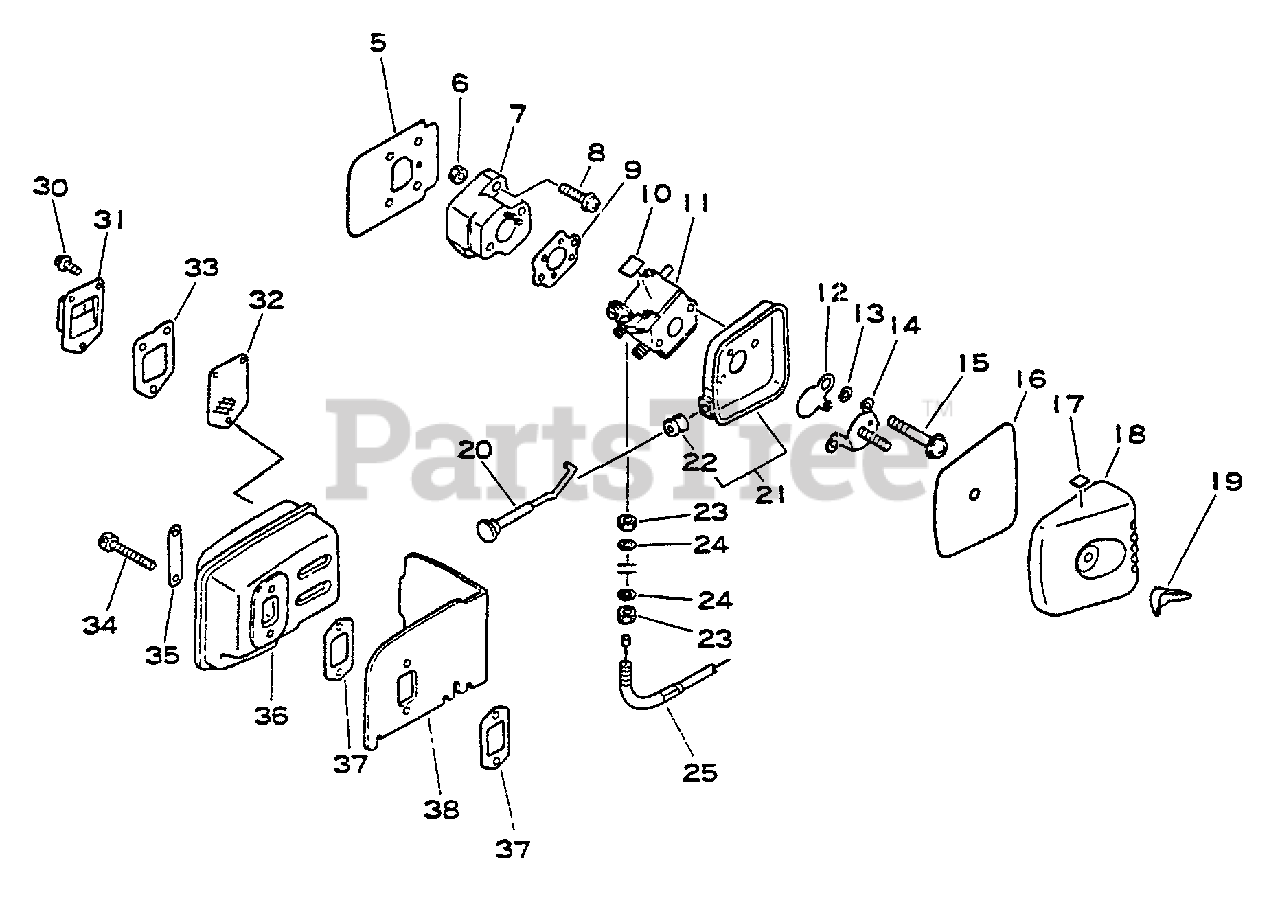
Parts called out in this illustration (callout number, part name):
5	HEAT SHIELD, INTAKE
6	NUT M5
7	INSULATOR, INTAKE
8	SCREW 5×20
9	GASKET, INTAKE
10	LABEL, CAUTION
11	CARBURETOR
12	SHUTTER, CHOKE
13	WASHER 5.2×8×0.8T
14	PLATE, PREVENT
15	SCREW 5×57
16	FILTER, AIR
17	LABEL, CHOKE
18	COVER, AIR FILTER
19	WINGNUT - 6
20	ROD, CHOKE
21	CASE, AIR FILTER
22	GROMMET, CHOKE
23	NUT 6 MM
25	CABLE, THROTTLE
30	SCREW 4×10
31	LID, MUFFLER
32	SCREEN, SPARK ARRESTER
33	GASKET, EXHAUST
34	BOLT 5×55
37	GASKET, EXHAUST
38	HEAT SHIELD, EXHAUST
